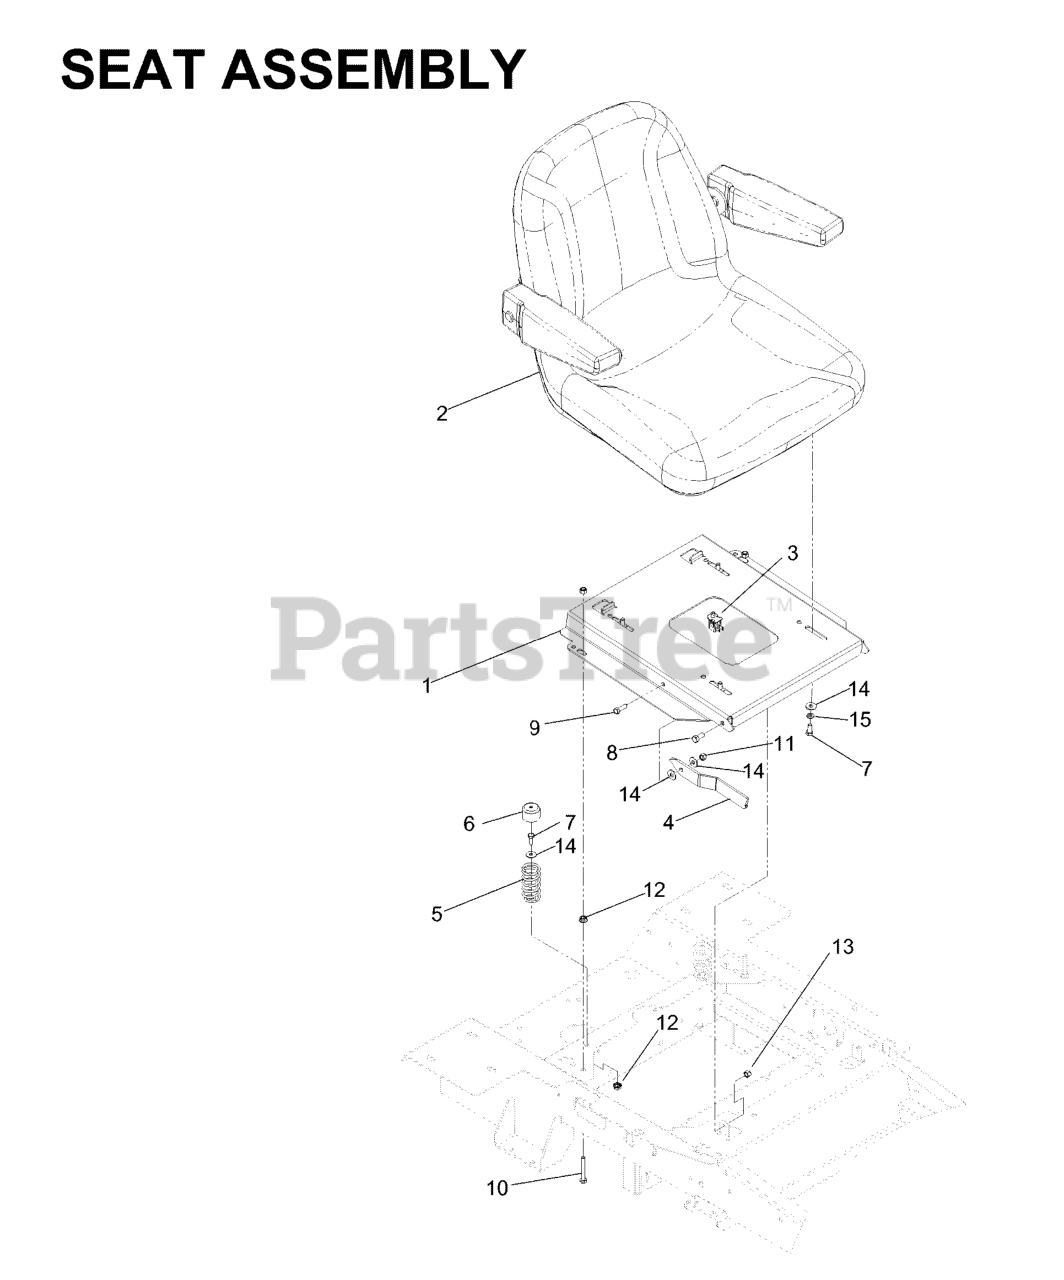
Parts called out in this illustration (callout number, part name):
2	SEAT W/ARMRESTS
3	SEAT SWITCH
4	ARM, PROP, SEAT
5	SEAT SPRING
6	SPRING CAP
7	HCS 5/16C X 3/4
8	SCREW 3/8C X 3/4 HEX CAP
9	HCS 5/16C X 1
10	TAP BOLT 5/16C X 2 1/4
11	NUT 5/16 NYLOC
12	NUT 5/16C WHIZ
13	NUT 3/8-16 NYLOC
14	WASHER 5/16 FLAT
15	WASHER.LOCK.HVY.HLCL.SPR.5/16
